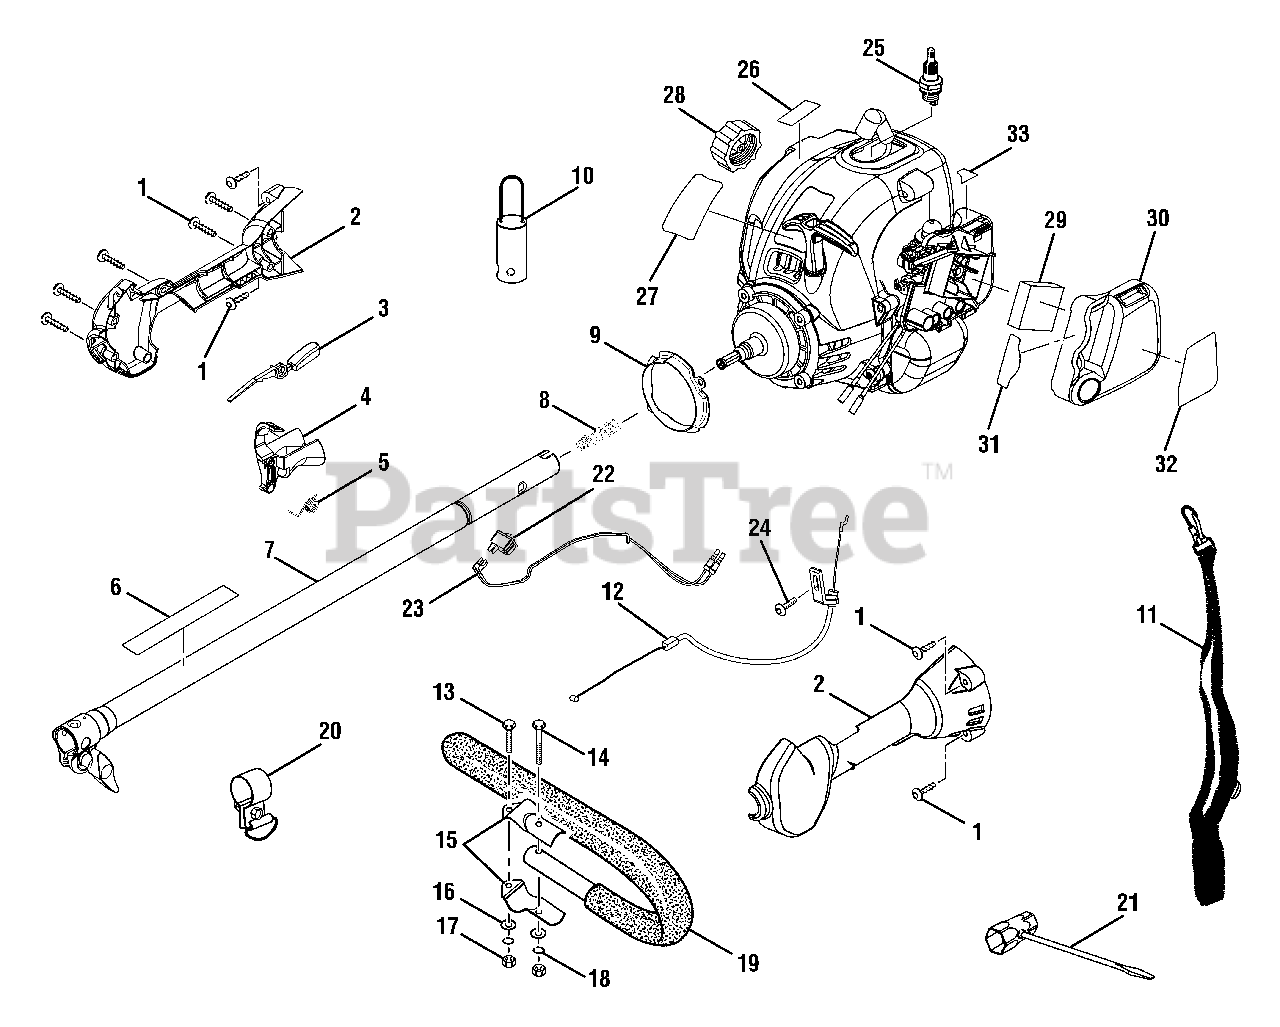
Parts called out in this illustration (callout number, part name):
1	SCREW (10-14 X 1 in. T.F. TRUSS HD.)
2	HANDLE ASSEMBLY
3	TRIGGER LOCK
5	TORSION SPRING
6	WARNING LABEL
7	BOOM ASSEMBLY
8	COMPRESSION SPRING
9	RING GUARD
10	STORAGE END CAP
11	SHOULDER STRAP
12	THROTTLE CABLE ASSEMBLY
13	BOLT (1/4-20 X 1 in. HEX HD.)
14	BOLT (1/4-20 X 1-1/2 in. HEX HD.)
15	HANDLE BAR CLAMP
16	WASHER
17	HEX NUT (1/4-20)
18	LOCK WASHER
19	J HANDLE AND GRIP
20	STRAP HANGER
21	COMBINATION WRENCH
22	SWITCH (MOMENTARY CONTACT)
23	LEAD ASSEMBLY
25	SPARK PLUG (CHAMPION RCJ6Y OR NGK BPM R7)
26	LOGO LABEL
27	DATA LABEL
28	FUEL CAP ASSEMBLY
29	AIR FILTER
30	AIR BOX COVER
31	CHOKE DECAL
32	STARTING LABEL
33	PRIMER LABEL
